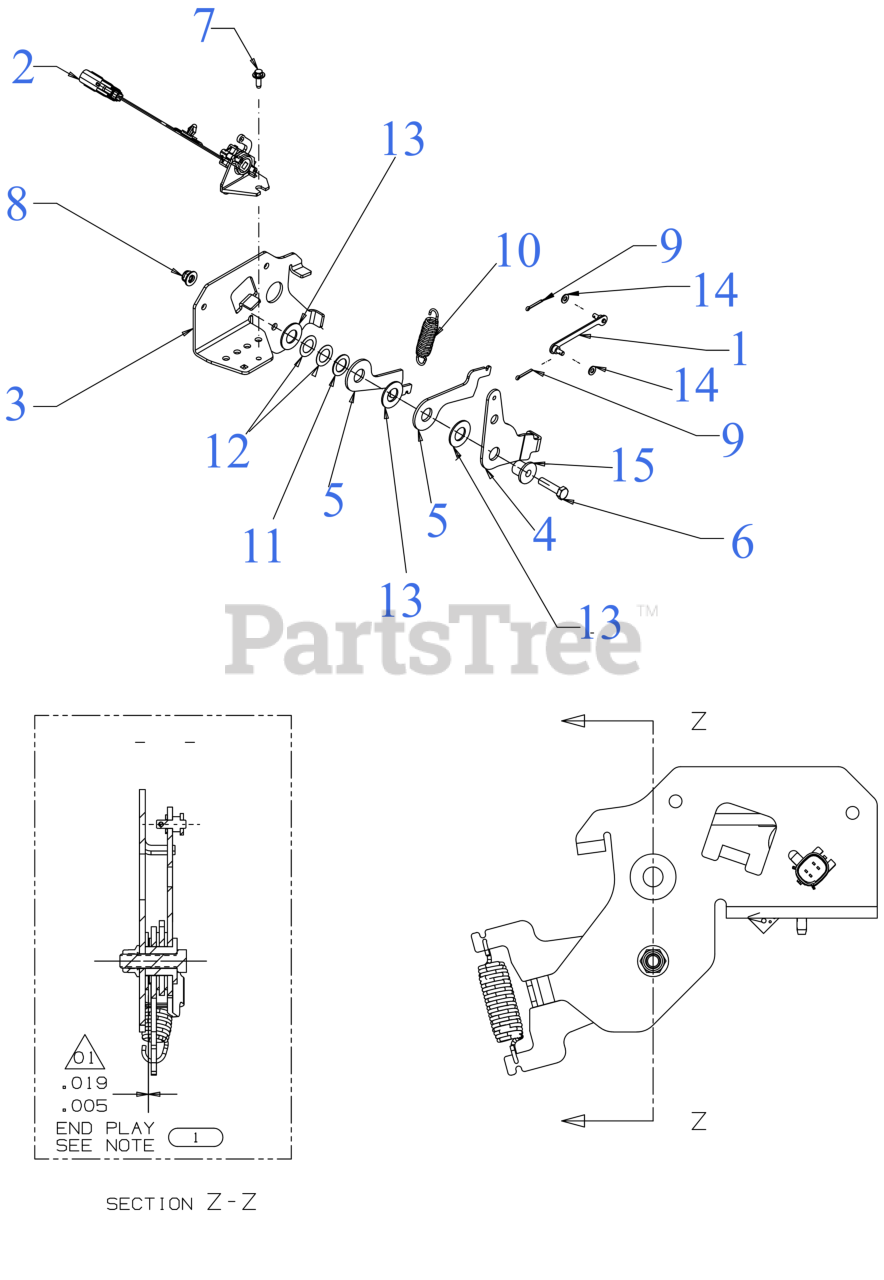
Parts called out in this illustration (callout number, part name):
1	CONTROL LINK (LH)
2	THROTTLE SENSOR ASSEMLBLY
2	HARNESS CLIP
2	ROTARY SENSOR MAGNET
3	CONTROL RETURN MOUNT (LH)
4	DRIVE CONTROL PLATE (LH)
5	CONTROL RETURN PLATE
6	SCREW 5/16-18 x 1.25 GR5
7	SCREW M6-1 x .625
8	FLANGE LOCK NUT 5/16-18
9	COTTER PIN 3/32
10	EXTENSION SPRING .65 OD x 2.65 LG
11	FLAT WASHER
12	SHIM WASHER .632X1.000X.010:HD
13	FLAT WASHER NYLON 5/8
14	FLAT WASHER .203 ID x .41 OD x .040
15	SHOULDER SPACER .32 x .625 x .66
